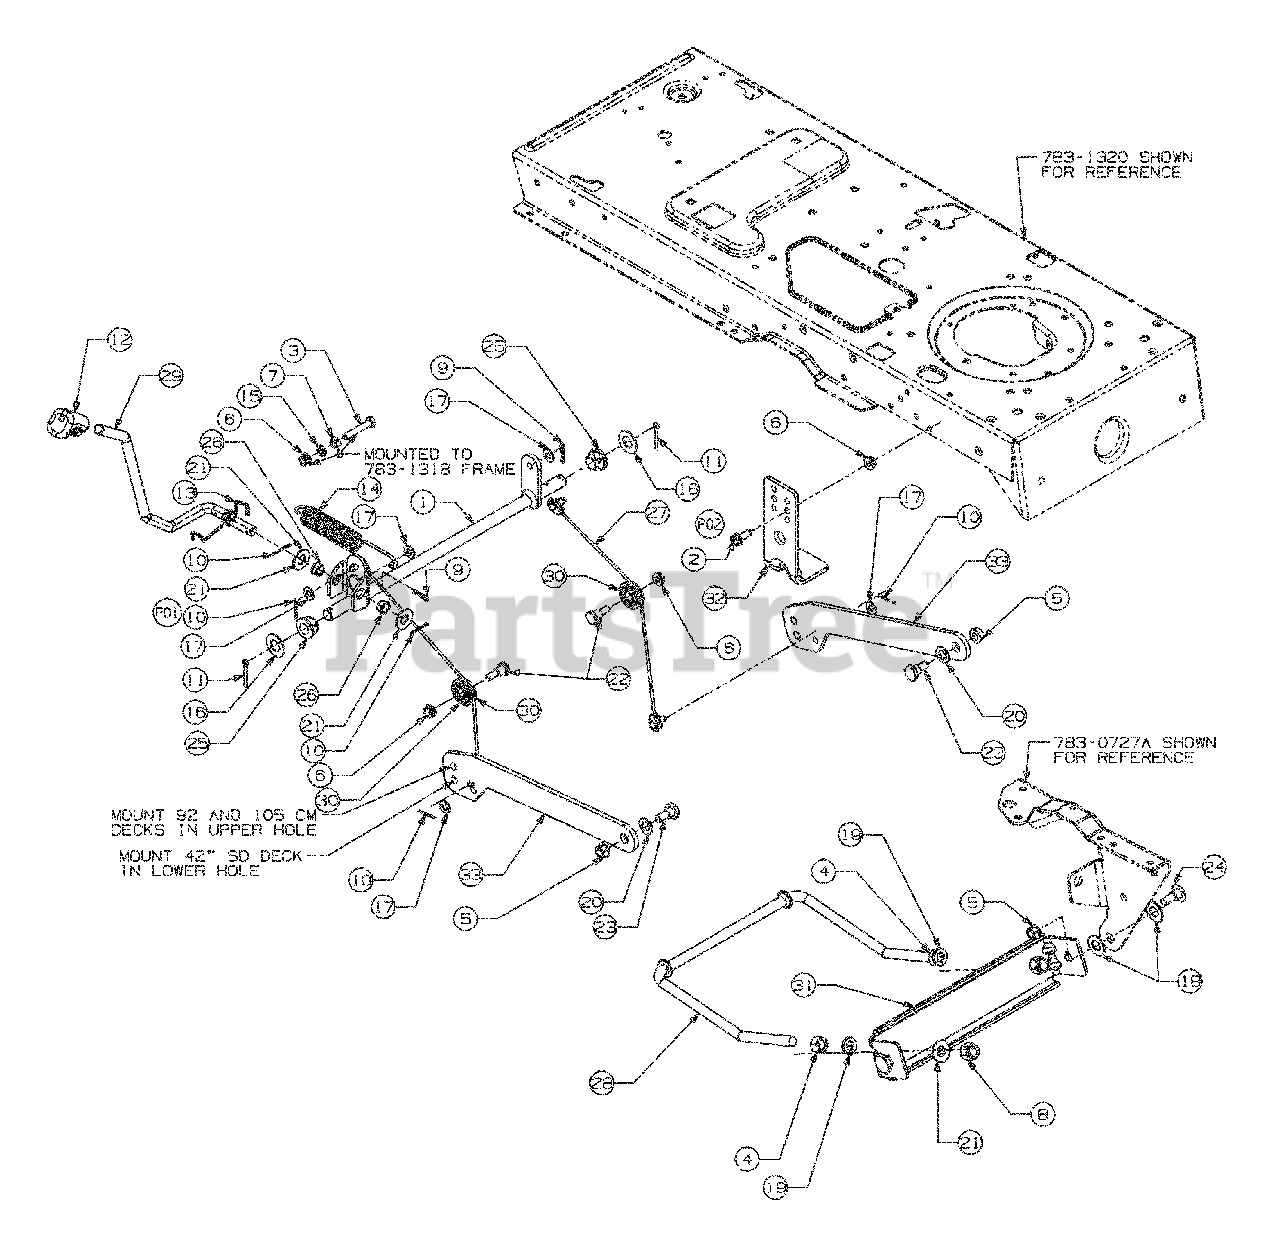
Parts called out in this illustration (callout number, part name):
2	SCR:TT:5/16-18:0.875:HXINDWSH
3	HHCS:5/16-18:1.75:GR5:STD
4	NUT:HEX:1/2-13:GR5
5	NUT:FLGLK:3/8-16:GRF:TOP LK
6	NUT:FLGLK:5/16-18:GR5:SD LK
7	NUT:HEX:5/16-18:GR5
8	NUT:HXLK:1/2-13:GR8:NYLON
9	PIN:COT:.072 DIA. X 1.13 LG
10	PIN:COT:3/32:1.0
11	PIN:COT:5/32:1.25
12	GRIP:HNDL:1/2
14	SPR:EXTN:1.010 OD X 6.500 LG
15	WASH:LOCK:5/16:REGULAR DUTY
16	WASH:FL .64 ID X 1.24 X .06
17	WASH:FLAT:.344 X .688 X .065
18	WASH:FLAT:.570X1.120X.062:TEFL
19	WASH:LOCK: 1/2 : REGULAR DUTY
20	WASH:FLAT:1/2X.875X.060
21	WASH:FLAT:.510 X 1.120 X .060
22	SCR:HEX CAP:5/16-18 X .620 GR2
23	SHLD SCR: 3/8-16
24	SCR:SHLDER:.500 DIA X .434
25	BRG:HEX FLNG
26	BRG:FLG:SNAP .500 ID
27	CBL:LIFT:14.06 LG
28	ROD:DECK:FRT ADJ .5" DIA
33	ARM:LIFT
